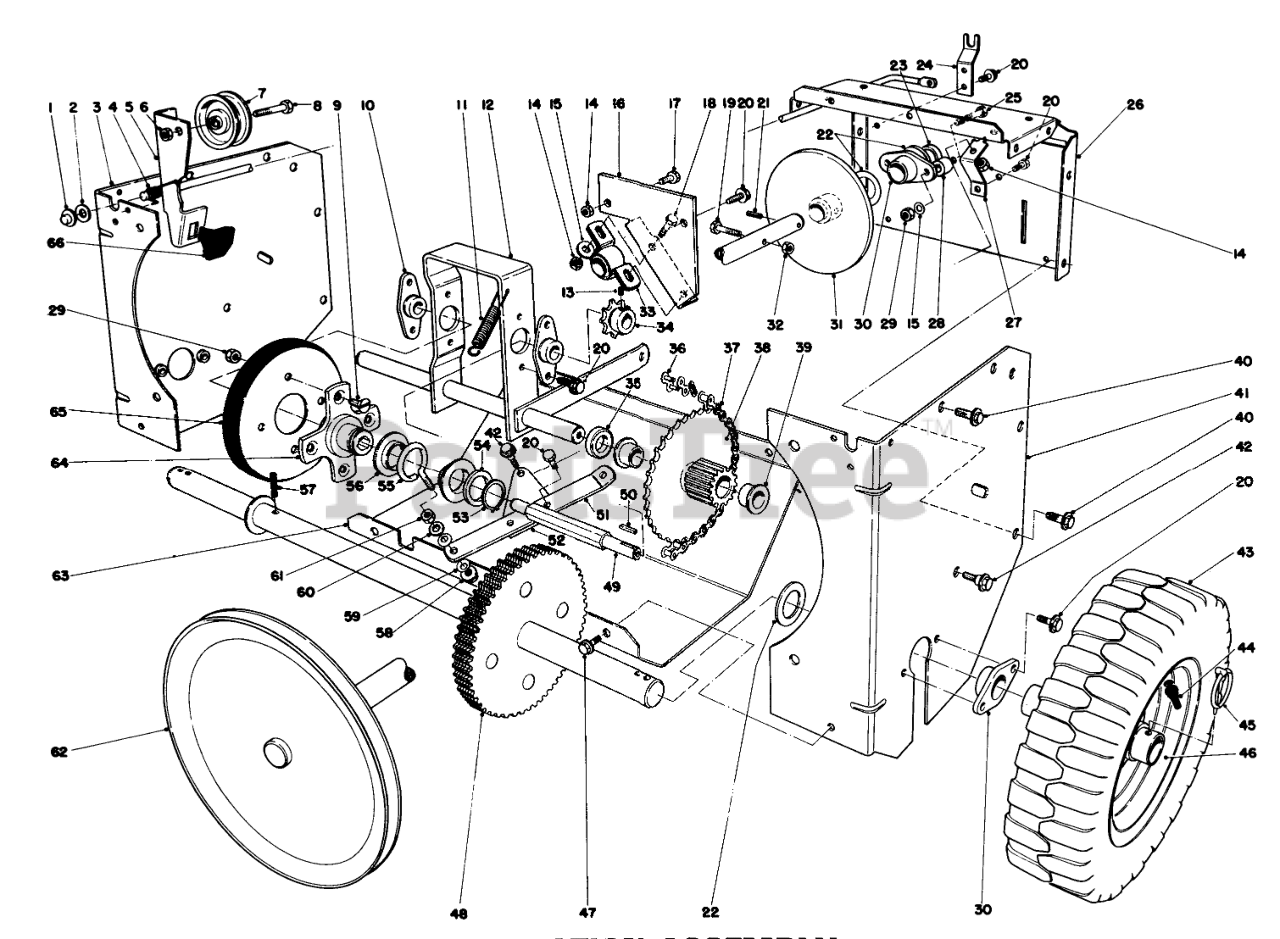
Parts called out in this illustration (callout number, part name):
1	PUSH NUT
2	WASHER-FLAT
3	RH TRACT SIDE PLT R
4	TORSION CLUTCH SPRING
5	Clutch Rod (Incl. Ref. #66)
6	NUT-HEX
7	PULLEY-IDLER
8	SCREW-HH
9	5/16-18X5/8 FLT HD MS
10	BEARING-WHEEL, FRICTION
11	TENSION SPRING
12	PIVOT SHAFT WA B
13	SCREW-HSH
14	NUT-LOCK, NI
15	WASHER-PLAIN
16	SHAFT SUPT BRKT B
17	SCREW-HH
18	SCREW-HH
19	SCREW-HH
20	SCREW-HWHTF
21	PIN-ROLL, SLOTTED
22	WASHER
23	DRIVE SHAFT SPACER
24	CLUTCH ROD SUPPORT
25	SCREW-HH
26	CENTER FRAME R
27	PIVOT BRACKET
28	BRG STANDOFF
29	Nut
30	AXLE BEARING
31	FRICTION PLT WA
32	NUT-LOCK, CONE
33	PILLOW BLOCK BRG
34	SPROCKET
35	COSHAFT SPACER
36	LINK-CONNECTING
37	ROLLER-CHAIN
38	Gear & Bushing (Incl. Ref. #39)
39	BUSHING
40	SCREW-HHFTF
41	LH TRACT SIDE PLT R
42	SHOULDER SCREW
43	Tire
44	STEM-VALVE
45	PIN-LYNCH
46	Wheel
47	SCREW-HWH
48	AXLE & GEAR WA
49	FRICTION WHL SHAFT
51	SHIFT LINKAGE
52	PIVOT PLATE
53	RING-RETAINING
54	WASHER-THRUST
55	SLIDER RING COLLAR
56	SLIDER RING
57	PIN-ROLL, SLOTTED
58	NUT-LOCK, FLANGE
59	WASHER-SPRING
60	WASHER-FLAT
61	Nut
62	PULLEY/SHFT WA
63	LOWER SHIELD R
64	TRACTION DISC HUB
65	FRICTION WHEEL
66	Brake Pad
